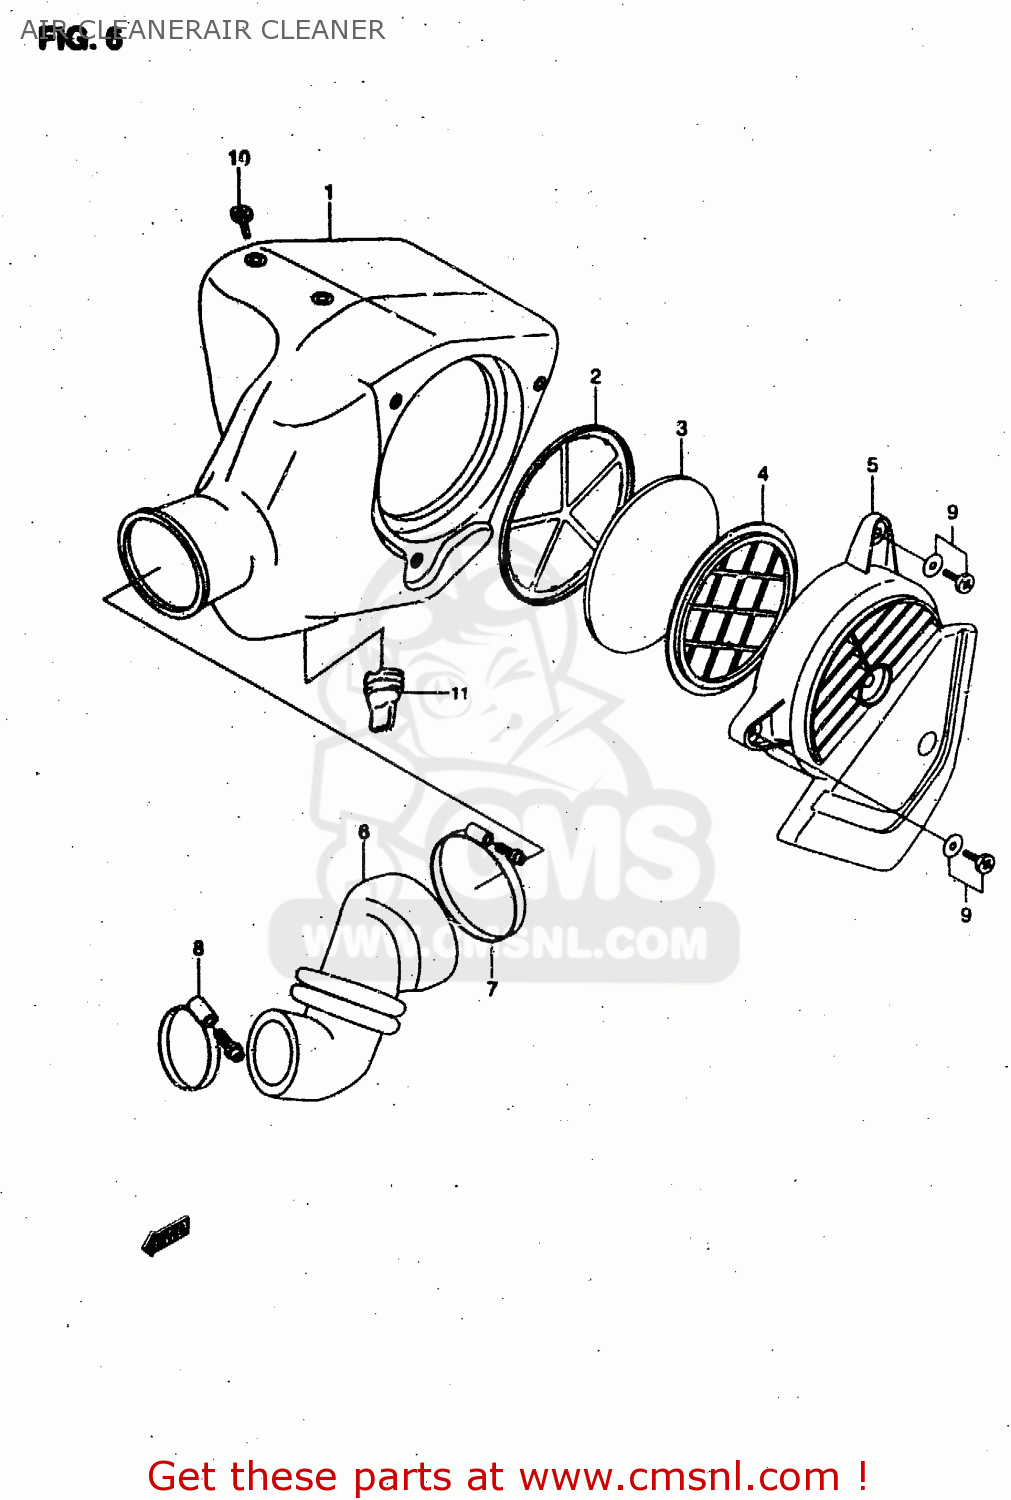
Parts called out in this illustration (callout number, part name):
1A	CLEANER, AIR
2	HOLDER, FILTER
3	FILTER
4	HOLDER
5	CAP, AIR CLEANER
6	TUBE, OUTLET
7	CLAMP
8	CLAMP
9	SCREW &WAHSER
10	SCREW
11	TUBE, DRAIN
